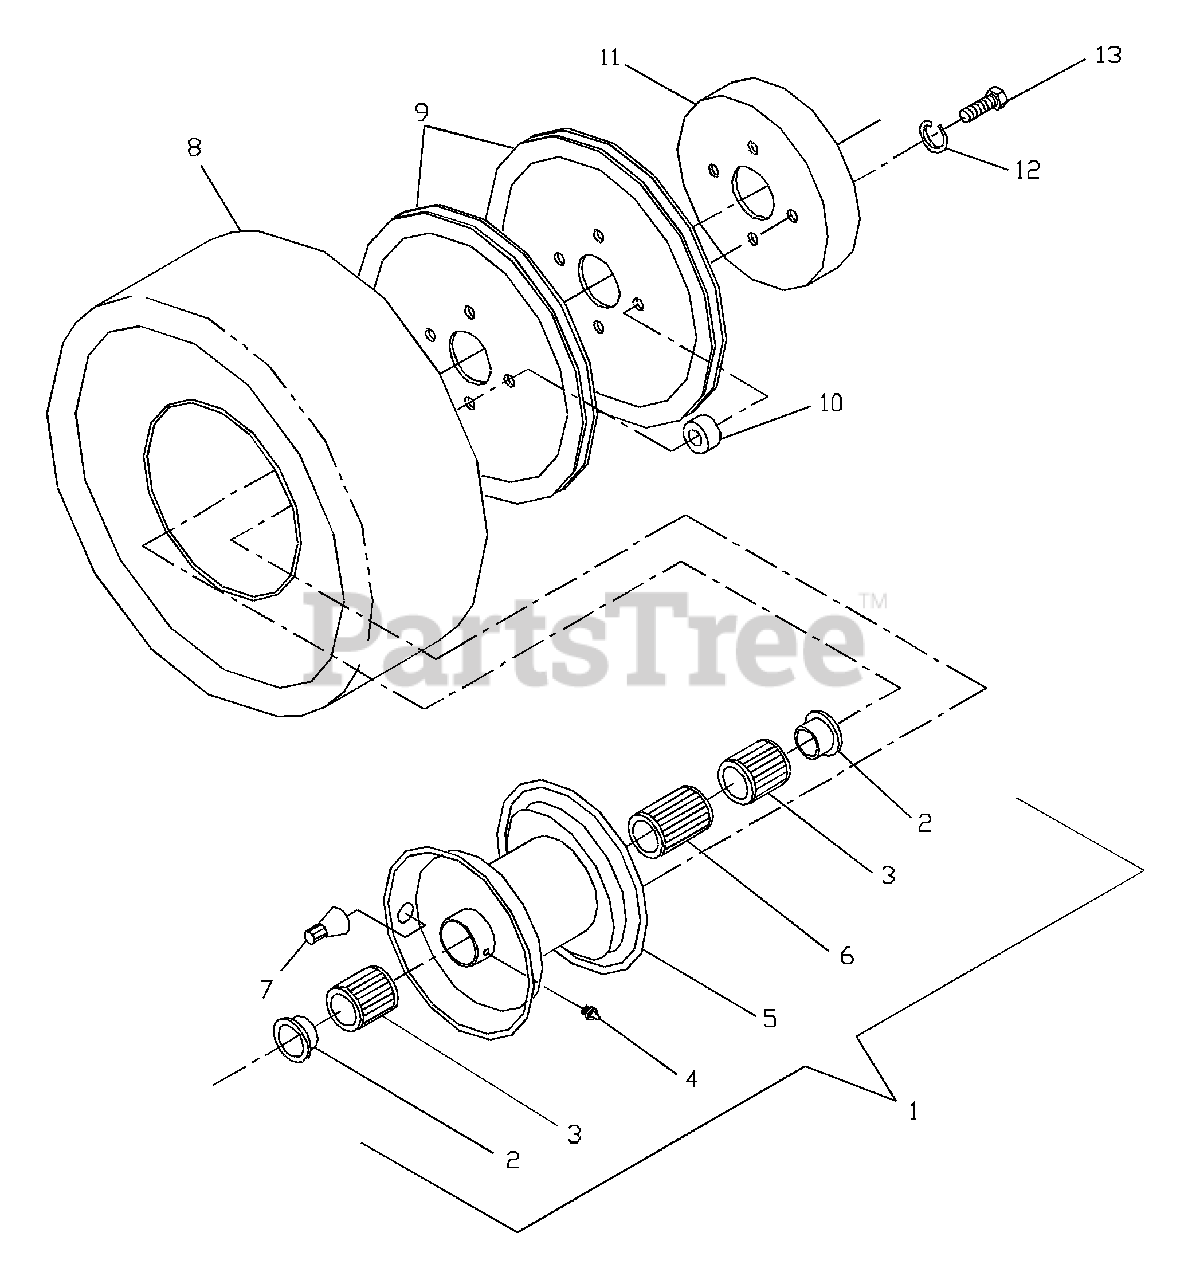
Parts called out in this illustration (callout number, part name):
1	WHEEL ASM.
3	ROLLER BEARING (SHORT)
4	ZERK 1/4-28 STRHT
5	RIM
6	ROLLER BEARING (LONG)
8	TIRE
9	TRACTION PULLEY
11	BRAKE DRUM
12	SLW 3/8 STD
13	HCS 3/8F X 1 1/2
